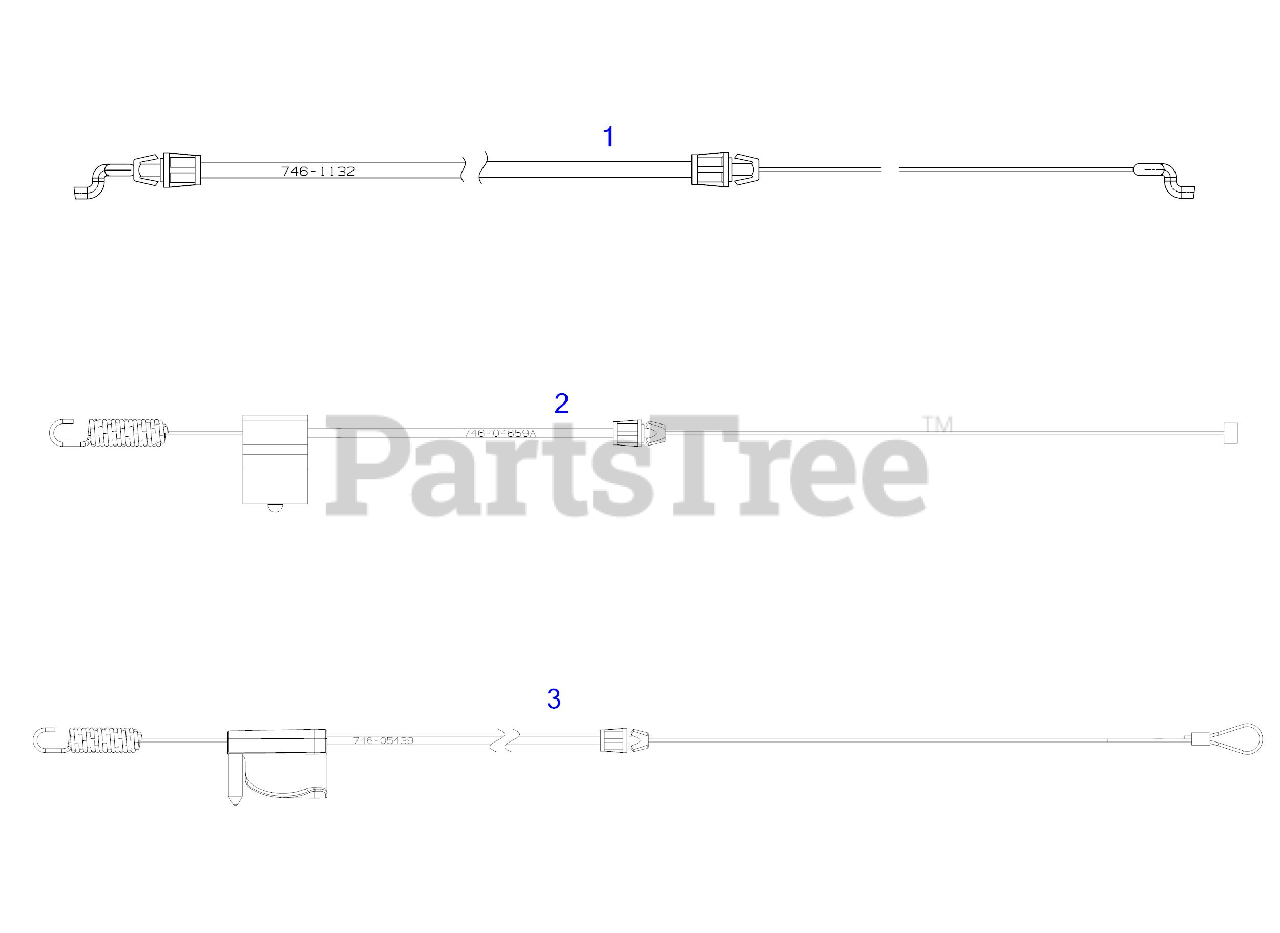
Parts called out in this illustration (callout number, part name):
1	CONTROL CABLE
2	SINGLE SPEED CABLE
3	SINGLE SPEED CABLE AWD
